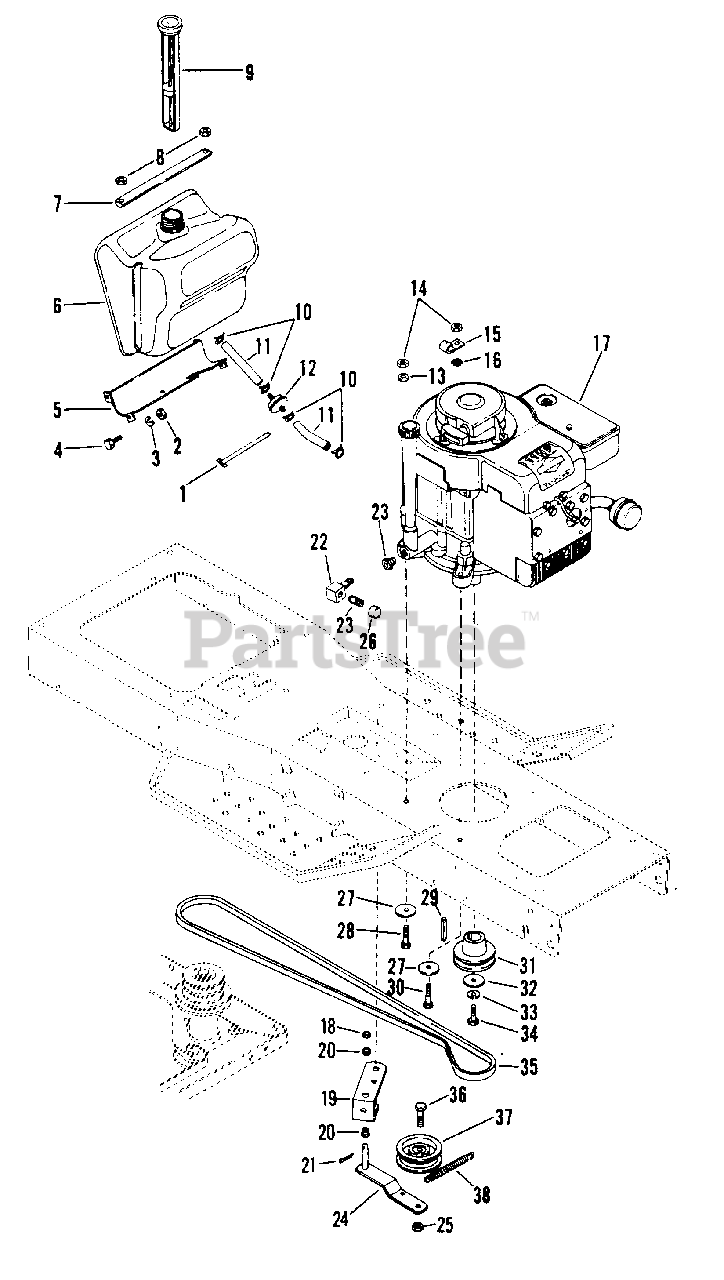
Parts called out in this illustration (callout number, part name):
1	TIE DOWN
2	NUT, HEX 1/4-20
3	WASHER, LOCK 1/4 REG.
4	BOLT, HEX 1/4-20X.50
5	SUPPORT, LOWER TANK
6	TANK, FUEL
7	STRAP, CLAMP
8	NUT, LOCK 1/4-20
9	GAUGE, FUEL
10	CLAMP, HOSE
11	LINE, FUEL
12	FILTER, FUEL
13	WASHER, FLAT .312X.734X.065
14	NUT, LOCK 5/16-18
15	CLIP
16	WASHER, LOCK 5/16 EXT. TOOTH TYA
17	ENGINE, 12 H.P. B&S
18	WASHER, FLAT .406X.812X.065
19	PIVOT, IDLER
20	BUSHING, FLANGE
21	PIN, COTTER .125X1.00
22	ELBOW, DRAIN
23	PIPE, OIL DRAIN
24	ARM, IDLER
25	NUT, LOCK 3/8-16
26	CAP, PIPE
27	WASHER, FLAT .312X1.625X.134
28	BOLT, HEX 5/16-18X1.50
29	KEY, SQUARE .25X2.0
30	BOLT, HEX 5/16-18X1.75
31	PULLEY, ENGINE
32	WASHER, FLAT .563X1.375X.109
33	WASHER, LOCK 7/16 SP HEAVY
34	BOLT, HEX 7/16-20X1.00
35	V-BELT
36	BOLT, HEX 3/8-16X1.50
37	IDLER
38	SPRING
